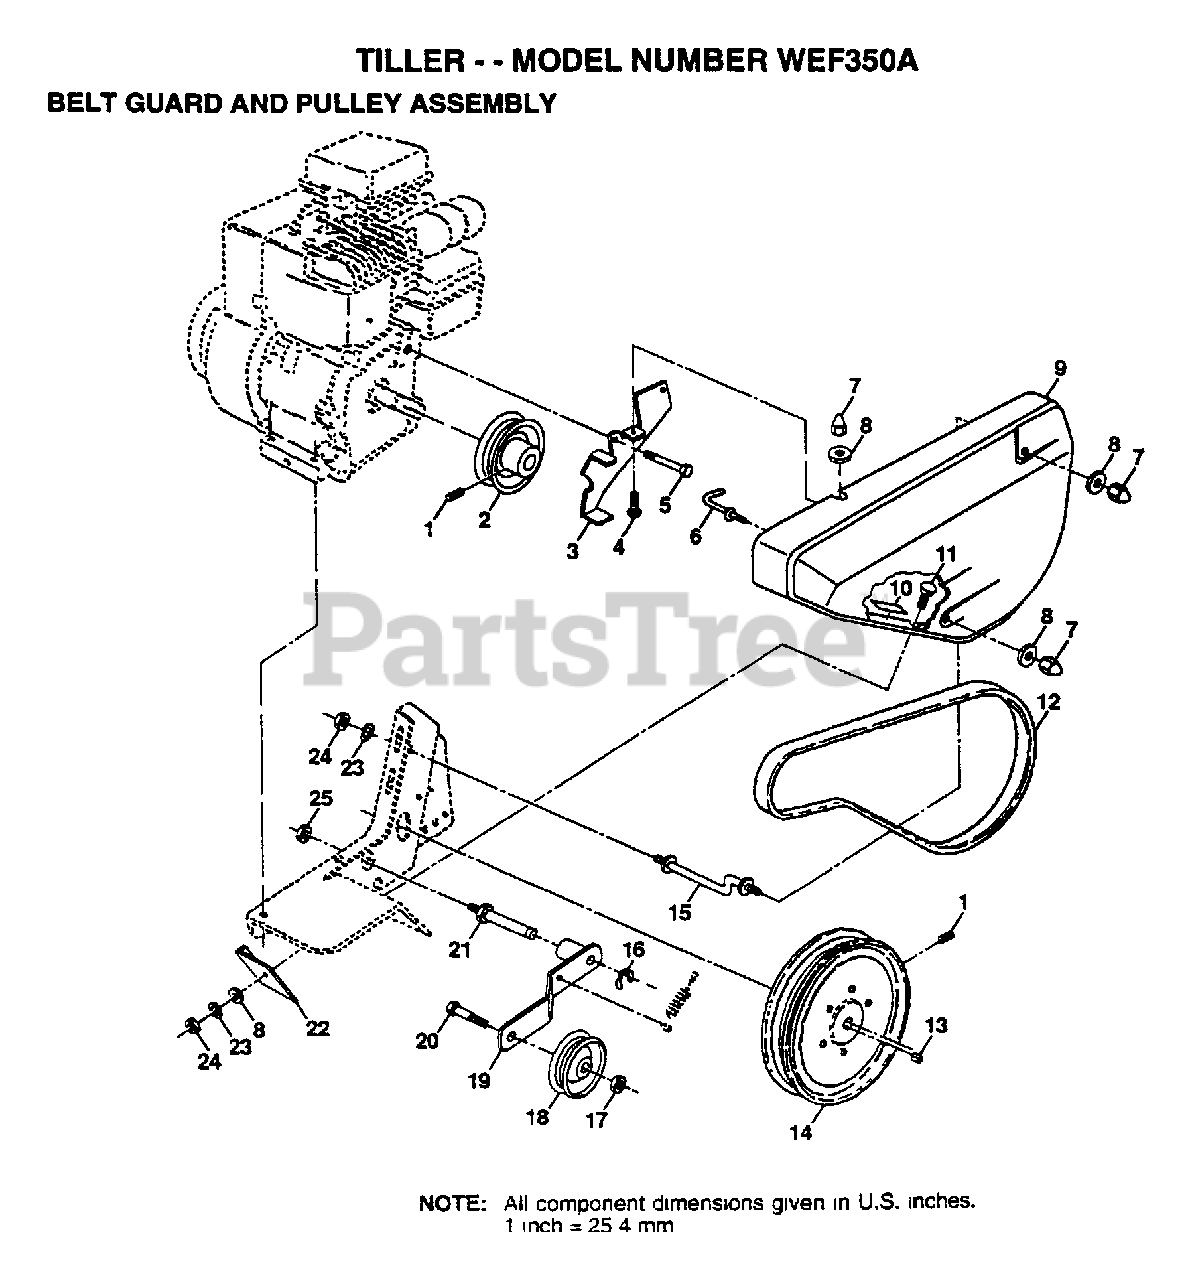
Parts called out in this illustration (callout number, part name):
1	SET SCREW
4	BOLT
7	NUT-CAP TI
8	WASHER
9	GUARD.BELT.TILLER
10	PAD IDLER TI
11	BOLT T
13	KEY T
14	TRANS SHEAVE RT
16	KLIP RING TI
17	NUT
19	IDLER ARM TI
21	SHAFT IDLER TI
22	SHIELD-DIRT TI
23	LOCKWASHER
25	JAM NUT TI
